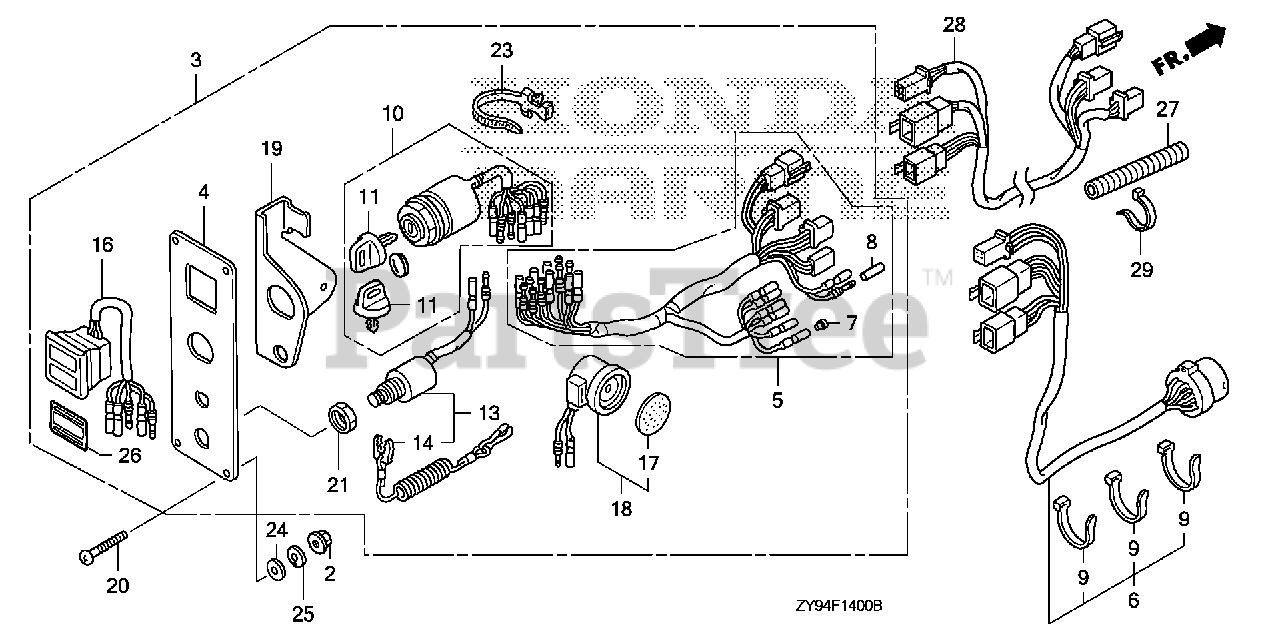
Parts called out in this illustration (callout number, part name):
2	NUT, FLANGE (5MM)
3	PANEL ASSY., CONTROL (2-LED)
4	PANEL, CONTROL
5	HARNESS ASSY., SWITCH PANEL
6	CABLE ASSY., SWITCH PANEL
7	PLUG, CONNECTOR (INNER)
8	PLUG, CONNECTOR (OUTER)
9	TIE, CABLE (2.4X92) (NATURAL)
10	SWITCH ASSY., COMBINATION
11	KEY ASSY., COMBINATION SWITCH (35100-ZV5-003 ONLY)
13	SWITCH ASSY., EMERGENCY STOP
14	WIRE, EMERGENCY
16	LAMP ASSY., INDICATION (2-LED)
17	PLATE, TURN SIGNAL BUZZER
18	BUZZER, WARNING
19	BRACKET, BUZZER
20	SCREW, PAN (5X40)
21	NUT, HEX. (16MM)
23	BAND, WIRE HARNESS (150MM) (NATURAL)
24	WASHER, PLAIN (5MM)
25	WASHER, SPRING (5MM)
26	MARK, SWITCH PANEL
27	TUBE, CORRUGATE (28MM)
28	CABLE ASSY., REMOTE CONTROL EXTENSION
29	BAND, SELF-LOCK
